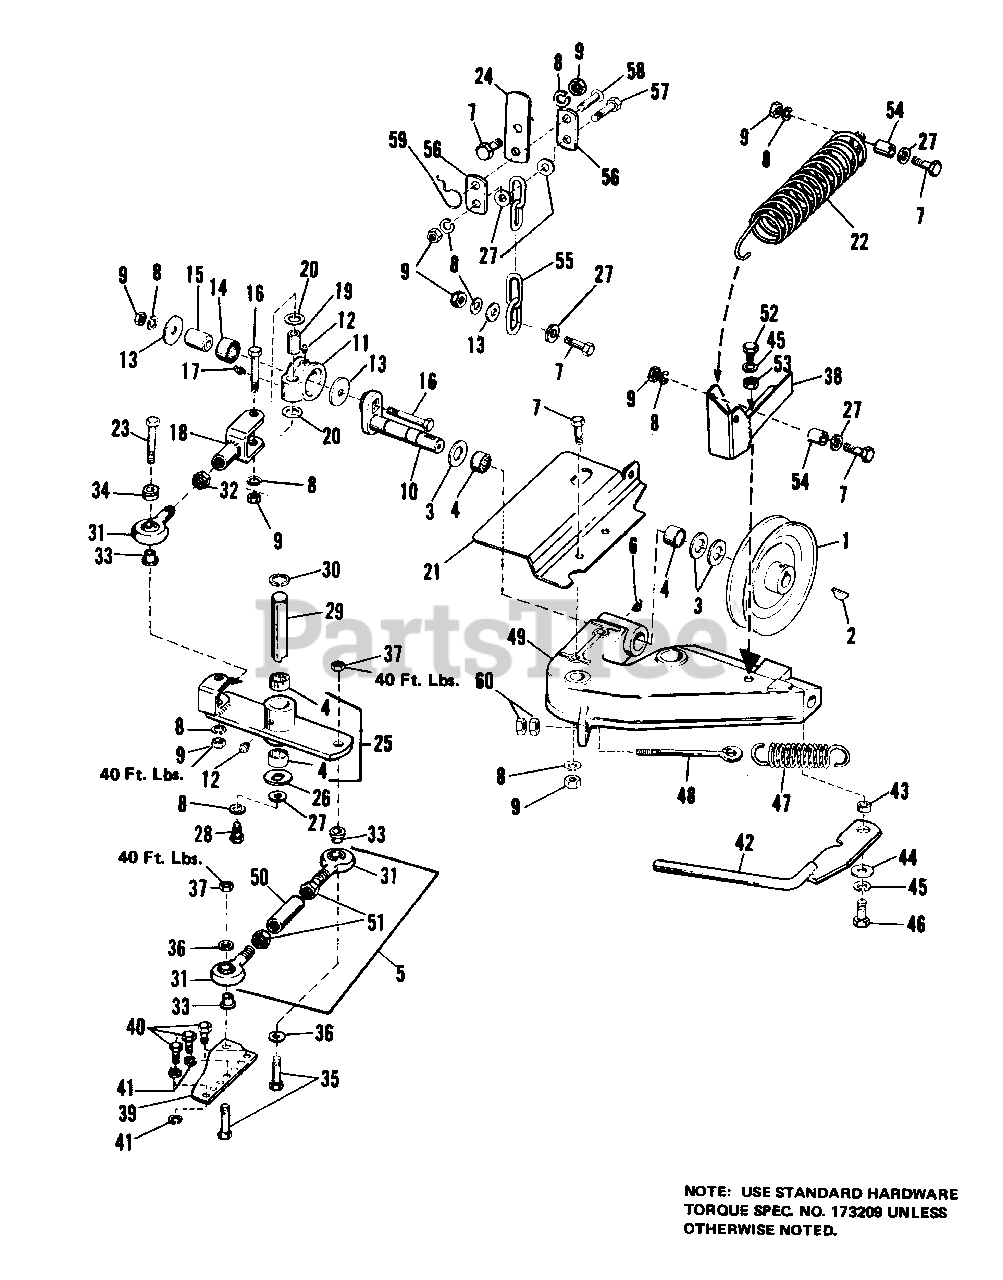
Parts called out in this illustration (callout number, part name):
1	PULLEY, Drive
2	KEY, Hi-Pro
4	BEARING, Needle
5	ROD ASSY, Connecting
6	FITTING, Grease
7	CAPSCREW, Hex Hd., 3/8-16 x 1
8	LOCKWASHER, 3/8
9	NUT, Hex, Full, 3/8-16
10	SHAFT, Crank
11	HOUSING, Pitman Bearing
12	FITTING, Grease
13	WASHER
14	BEARING, Needle
15	RACE, Inner Pitman
16	CAPSCREW, Hex Hd., 3/8-16 x 2-1/4
17	FITTING, Grease
18	CLEVIS ASSY, Pitman
19	BEARING, Pivot Block
23	CAPSCREW, Hex Hd., 3/8-16 x 2-1/2
24	CHAIN, Support
25	ROCKER ARM ASSY, w/Bearings
27	WASHER, Plain, 3/8
28	CAPSCREW, Hex Hd., 3/8-16 x 3/4
29	SHAFT, Rocker Arm
30	RING, Retaining
32	NUT, Hex, Full, 1/2-20
35	CAPSCREW, Hex, 3/8-24 x 1-3/4
37	LOCKNUT, Hex, Full, 3/8-24
38	MOUNTING ASSY, Cable
39	HEAD, Sickle
40	CAPSCREW, Hex Hd., 5/16-24 x 1/2
41	LOCKWASHER, 5/16
42	LATCH ASSY
43	SPACER, Latch
44	WASHER, Plain
45	LOCKWASHER, 7/16
46	CAPSCREW, Hex Hd., 7/16-14 x 1-1/4
48	BOLT, Eye
49	HINGE ASSY
50	PIVOT, Connecting Rod
51	NUT, Jam, Hex, 1/2-20
52	CAPSCREW, Hex Hd., 7/16-14 x 1-3/4
53	NUT, Hex, Full, 7/16-14
55	CHAIN, Lift
56	LINK, Mower Lift
57	CAPSCREW, Hex Hd. 3/8-16 x 1-1/4
59	CLIP, Spring
60	NUT, Hex, Full, 5/16-18
